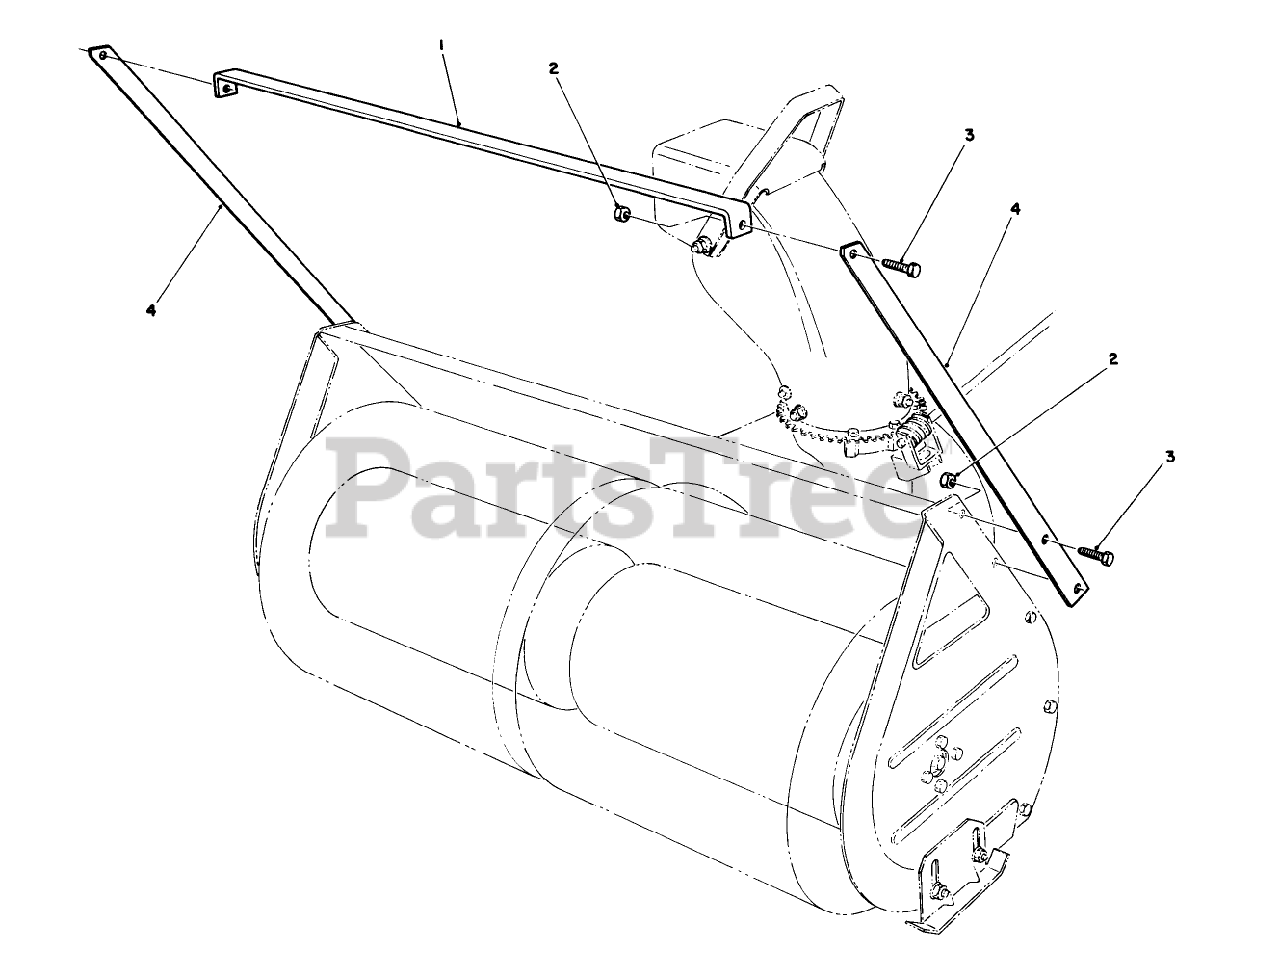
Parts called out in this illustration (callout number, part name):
1	32 TOP DRIFT BREAKER
2	NUT-LOCK, CONE
3	SCREW-HH
4	SIDE DRIFT BREAKER
